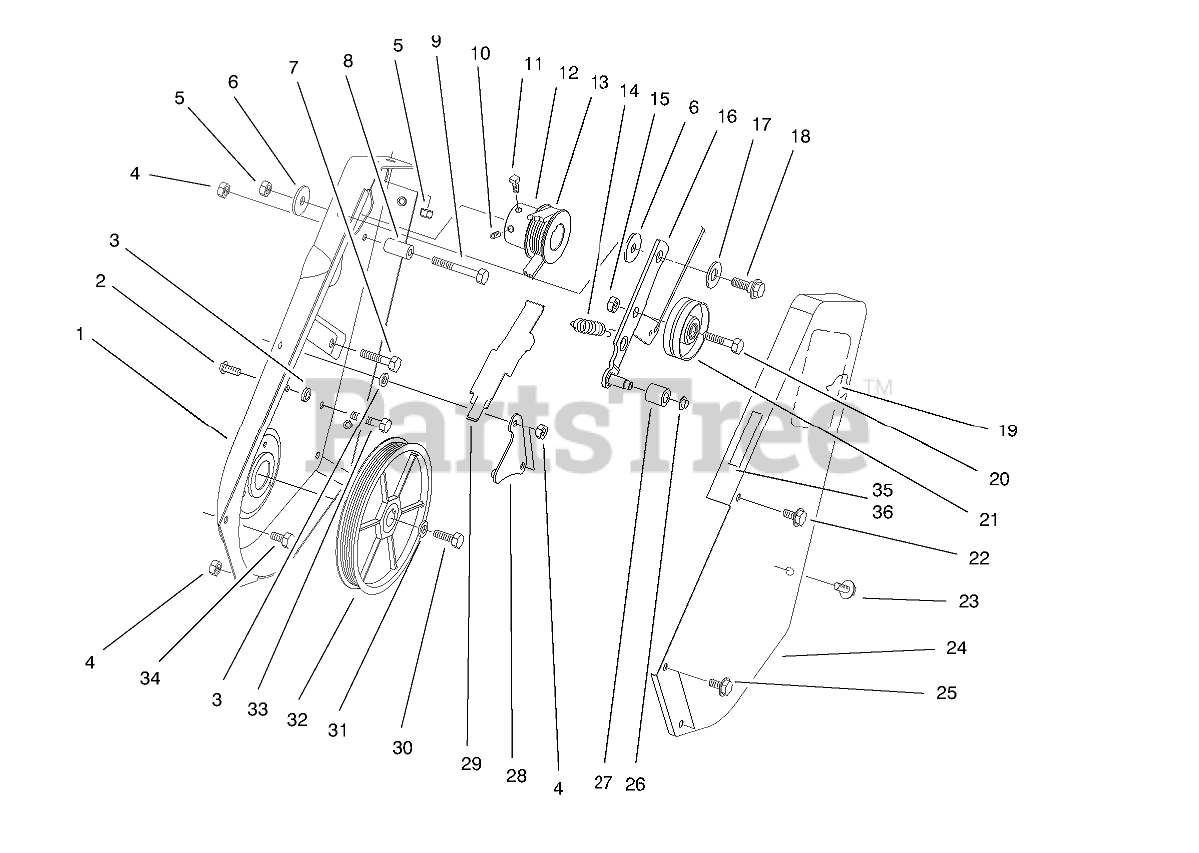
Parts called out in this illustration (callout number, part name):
1	Sideplate-LH
2	SCREW-HSBH
3	SPACER-PLATE, PIVOT
4	NUT-LOCK, NI
5	NUT-LOCK, NI
6	WASHER-PIVOT
7	SCREW-HH
8	SLEEVE-GUIDE, BELT
9	SCREW-HH
10	SCREW-HSH
11	SCREW-SQH
12	ENGINE PULLEY
13	BELT - DRIVE
14	SPRING-EXTENSION
15	NUT-LOCK, CONE
16	IDLER ARM ASM
17	WASHER
18	SCREW-SHOULDER
19	DECAL
20	SCREW-HH
21	PULLEY-IDLER
22	SCREW-HWH, TAP
23	SCREW
24	Cover-Drive
25	SCREW-HWH
26	NUT-PUSH
27	ROLLER-BRAKE
28	PIVOT PLATE ASM
29	BRAKE-ARM
30	SCREW-HH
31	WASHER-BELLEVILLE
32	ROTOR PULLEY ASY
33	SCREW-HH
34	SCREW-SHH
35	Decal-Hot
36	DECAL-HOT
